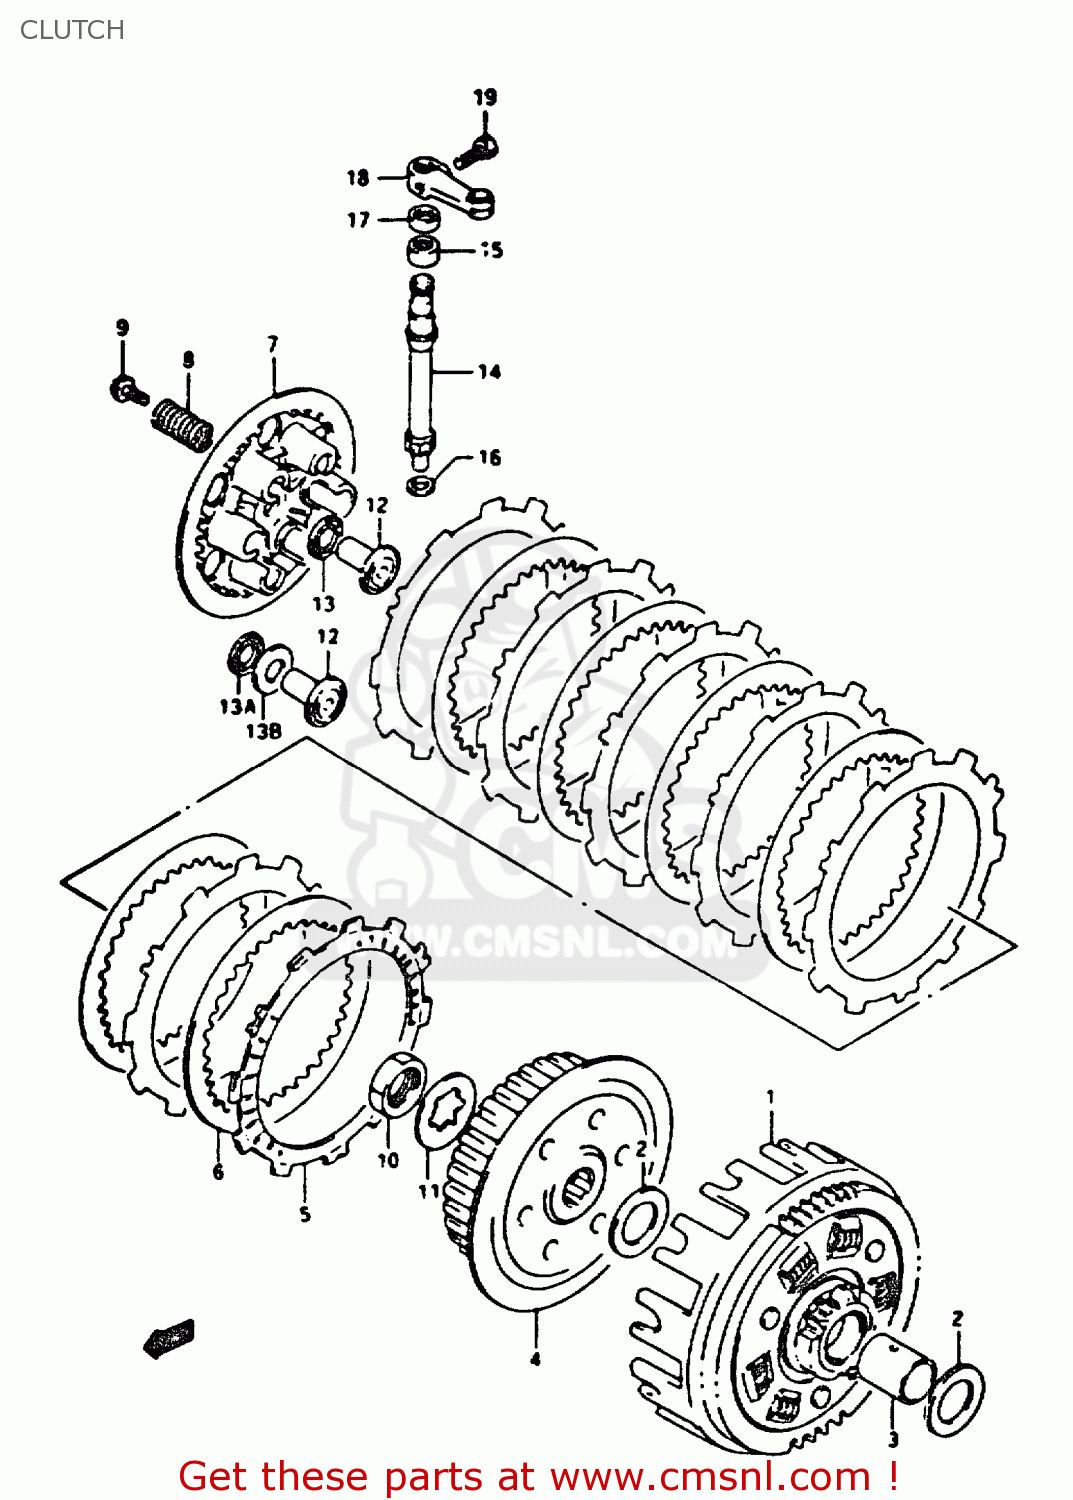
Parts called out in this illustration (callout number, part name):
1	GEAR ASSY,PRI DRIVEN(62/15
2	WASHER
3	SPACER(20X25X29)
4	HUB,CLUTCH SLEEVE
5	PLATE,CLUTCH DRIVE (NAS)
6	PLATE,CLUTCH DRIVEN (NAS)
7	DISC,CLUTCH PRESSURE
8	SPRING
9	BOLT 5X16
10	NUT (20MM)
11	WASHER,LOCK
12	RACK,CLUTCH RELEASE
13	BEARING(10X22X2.8)
13A	BEARING(10X24X2)
13B	WASHER
14	PINION,CLUTCH RELEASE
15	BEARING(12X16X10)
16	WASHER
17	SEAL,OIL(10X17X5)
18	ARM,CLUTCH RELEASE
19	BOLT
